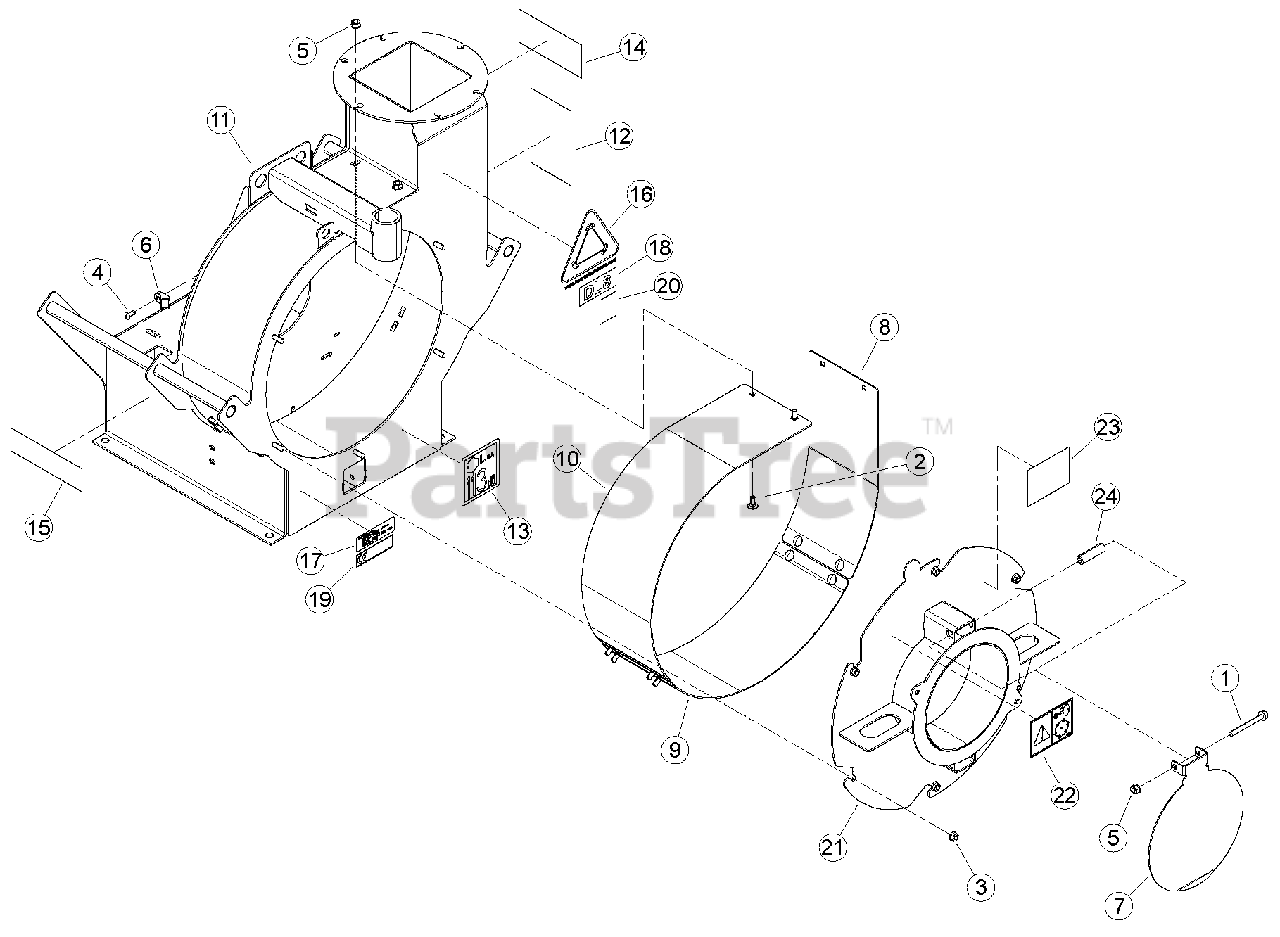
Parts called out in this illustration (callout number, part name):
1	BOLT, 5/16 X 3 FLANGE NC
2	BOLT, 5/16 X 3/4 GR5 CRG NC ZP
3	NUT, 5/16 FLANGE TOPLOCK
4	RIVET, AL BLIND 1/4 X 3/4 DOME HEAD
5	NUT, 5/16-18 NYLOCK-FLANGE
6	CLAMP, CABLE MOUNT
7	SHIELD, INTAKE
8	LINER, WEAR RIGHT
9	LINER, WEAR MIDDLE
10	LINER, WEAR LEFT
11	ASSEMBLY, DL8 HOUSING
12	DECAL, OPERATING INSTRUCTIONS ISO
13	DECAL, 113 DB
14	DECAL, MUTILINGUAL MANUAL
15	DECAL, ECHO BEARCAT 6.82 X 1.90
16	DECAL, COLLECT IT
17	DECAL, ATLANTIC BRIDGE LTD INFO
18	DECAL, MODEL DL8
19	DECAL, DL8 INFORMATION
20	DECAL, ECHO BEARCAT QR CODE
21	ASSEMBLY, VACUUM INTAKE
22	DECAL, INSTRUCTION ISO
23	DECAL, INSTRUCTION ISO
24	SPACER, 5/8 OD X 11 GA X 2.13
